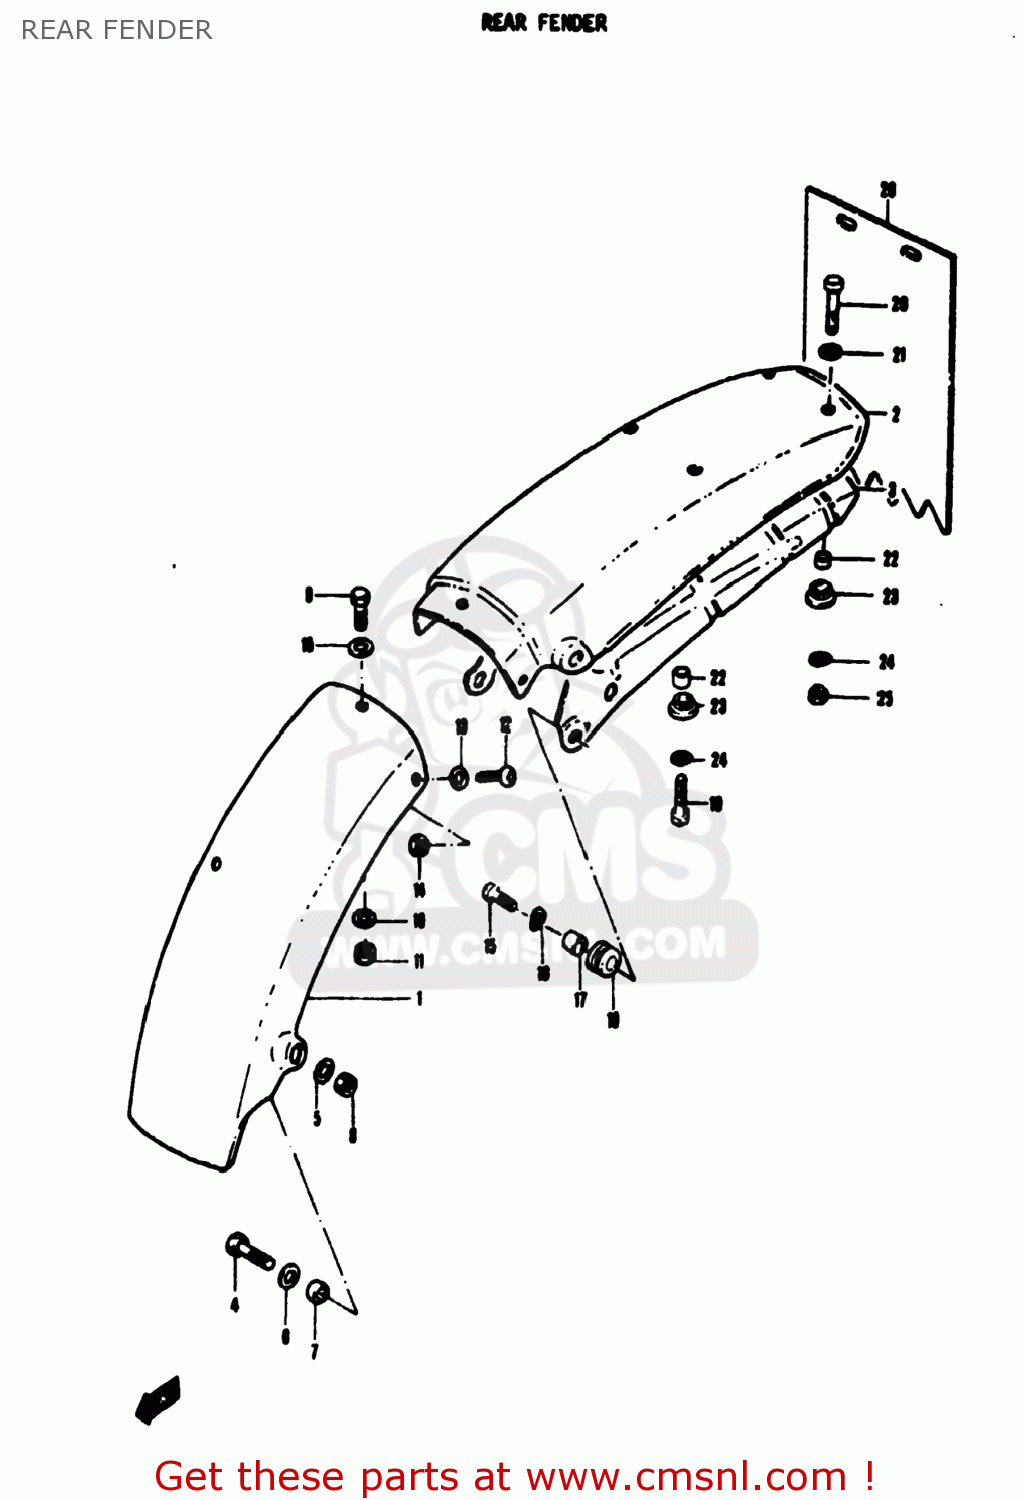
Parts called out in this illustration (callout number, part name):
1	FENDER,REAR
2	FENDER,REAR
3	REINFORCEMENT,REAR FENDER
4	BOLT
5	WASHER 6MM
6	WASHER
7	SPACER
8	NUT
9	BOLT
10	WASHER(6.5X16X1.2)
11	NUT
12	SCREW
13	WASHER 5MM
14	NUT
15	BOLT
16	LOCK WASHER
17	SPACER(6.1X9X7.5)
18	CUSHION
19	BOLT(6X18)
20	BOLT
21	WASHER 6MM
22	SPACER
23	CUSHION
24	LOCK WASHER
25	NUT
26	MUD GUARD,REAR FENDER
